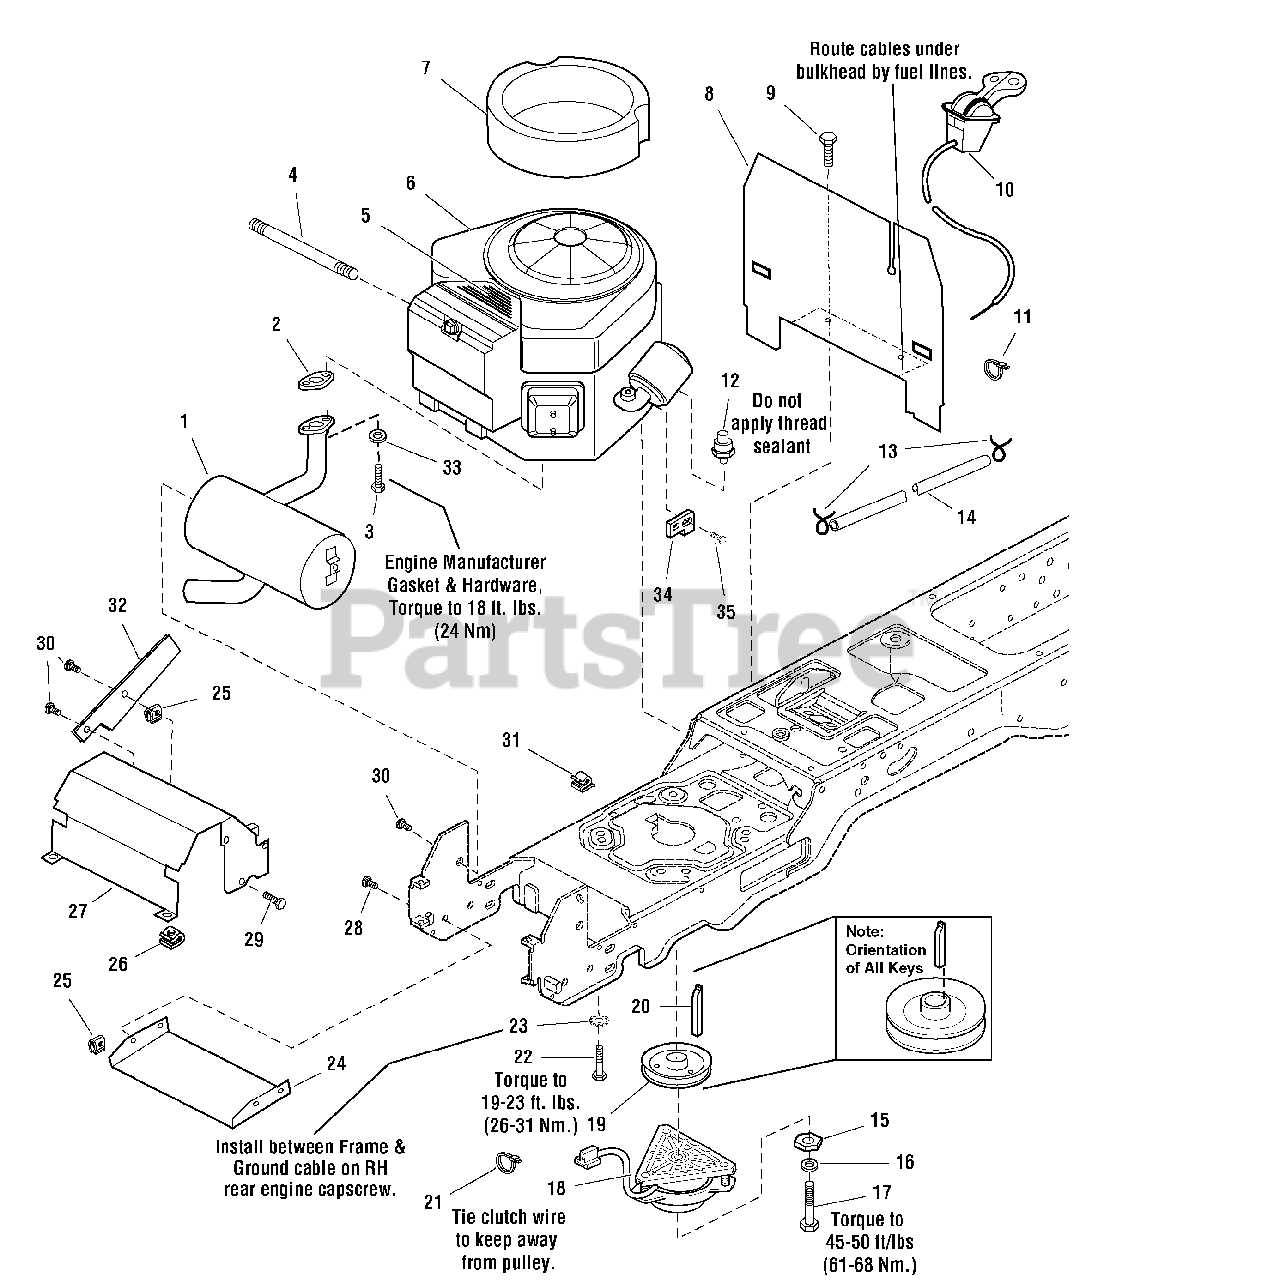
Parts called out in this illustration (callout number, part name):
1	MUFFLER, Briggs & Statton 16HP
2	* GASKET
3	CAPSCREW, 5/16-18 x 3/4
4	HOSE, Oil Drain
7	SEAL, Circle
8	BULKHEAD
9	CAPSCREW, Hex Head Taptite, 1/4-20 x 1/2
10	CONTROL, Throttle
11	TIE, Wire
12	SWITCH, Oil Pressure, 16HP
13	CLAMP, Hose Type E
14	HOSE, Fuel, 58" Long
15	WASHER, Special
16	LOCKWASHER, 7/16
17	CAPSCREW, Hex Head, 7/16-20 x 2-3/4
18	CLUTCH, Electric, Ogura
19	PULLEY & HUB ASSEMBLY
20	KEY, Hi Pro, 1/4 x 2-1/4
21	TIE
22	CAPSCREW, Hex Head Taptite, 3/8-16 x 1-1/2
23	LOCKWASHER, External Tooth 3/8
24	SHIELD, Muffler Bottom
25	NUT, Speed, 1/4-20
26	NUT, Speed, Lug Type, 5/16-18
27	DUCT, Muffler Top
28	CAPSCREW, Hex Head Flange Lock, 1/4-20 x 5/8
29	CAPSCREW, Hex Head Taptite, 1/4-20 x 3/8
30	CAPSCREW, Hex Head Taptite, 5/16-18 x 1/2
31	CLIP, Wire
32	GUARD, Manifold Pipe
33	LOCKWASHER, 5/16
34	PLATE, Limiter RPM
35	SCREW, Torx Taptite, #8-32 x 1/2
